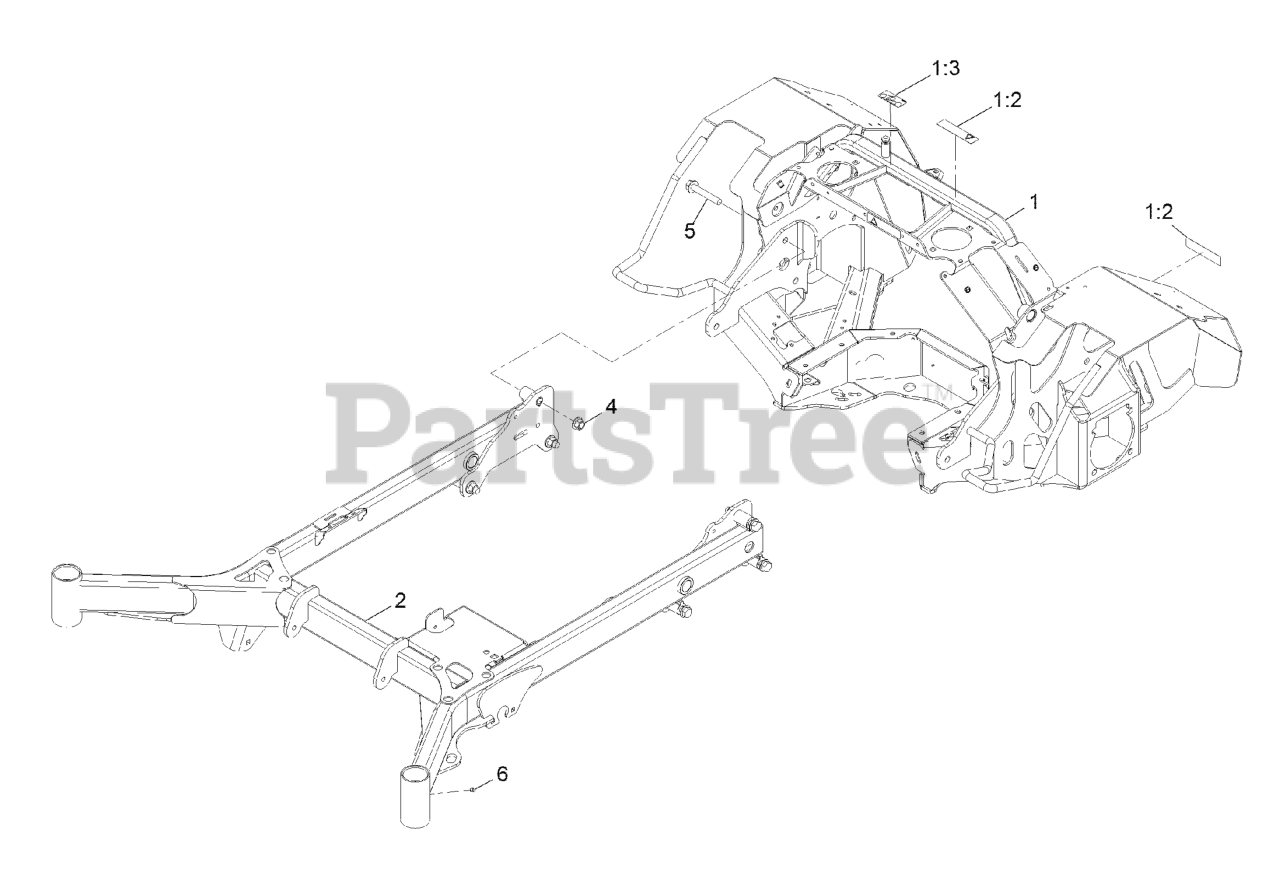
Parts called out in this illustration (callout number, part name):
1	ASM, REAR FRAME W/ DECALS
1:2	DECAL-WARNING
1:3	DECAL-BELT ROUTING HYD
2	WELD, FRONT FRAME, 60
4	Nut-Lock 1/2-13
5	SCREW-HF
